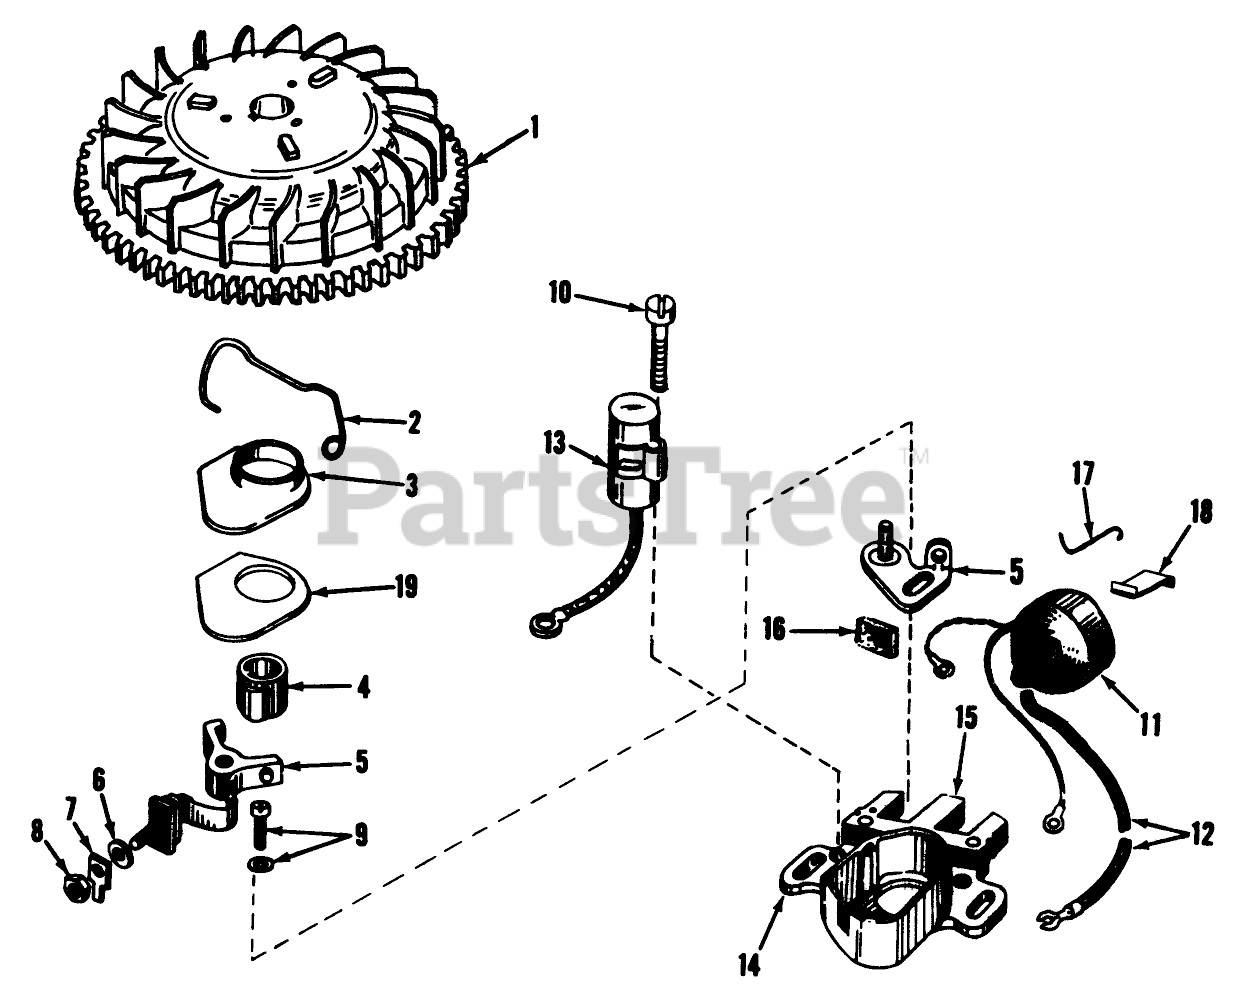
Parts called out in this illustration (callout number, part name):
1	Flywheel
2	Spring Breaker Box
3	Cover, Dust
4	Cam-Breaker
5	Contact Assy., Breaker
6	Washer
7	Terminal
8	DECAL
9	Breaker Screw
10	Condenser Screw
11	Coil Assy. (Incl. No. 12)
12	Wire, Lead
13	Condenser
14	Core Plate
15	Stator Assy., (Incl. Nos. 2, 3, 5 thru 14 16 thru 19)
16	Felt,Cam Wiper
17	Clip, Coil
18	Spring Coil Wedge
19	Gasket Dust Cover
